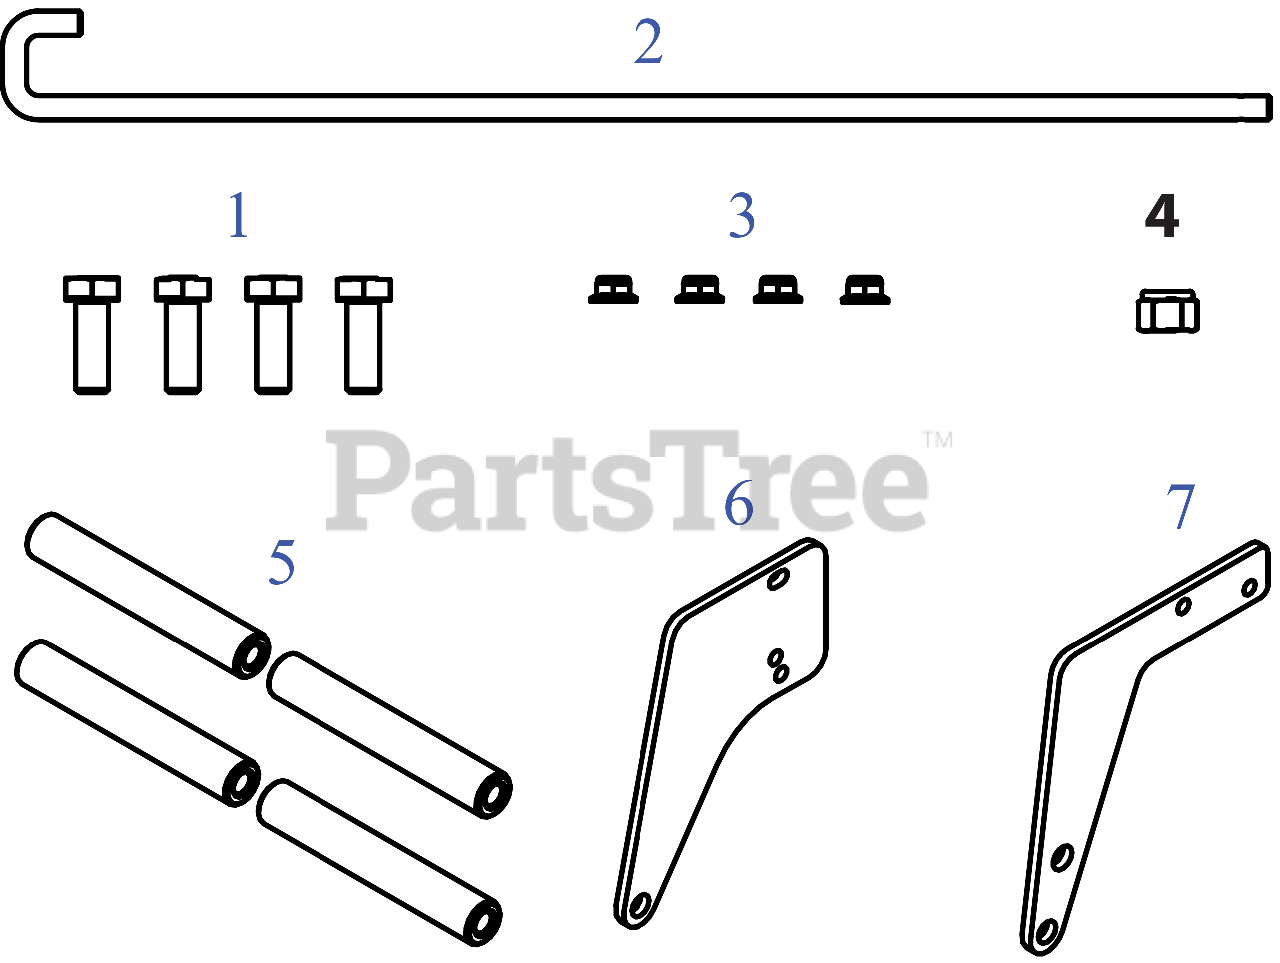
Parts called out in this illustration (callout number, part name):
1	SCREW 5/16-18 x .875 GR5
2	ROLLER PIN (.5"x30.25")
3	FLANGE LOCK NUT 5/16-18
4	HEX LOCK NUT NYLON
5	DECK STRIPING ROLLER
6	SUPPORT BRACKET (LH)
7	ROLLER SUPPORT BRACKET (RH)
